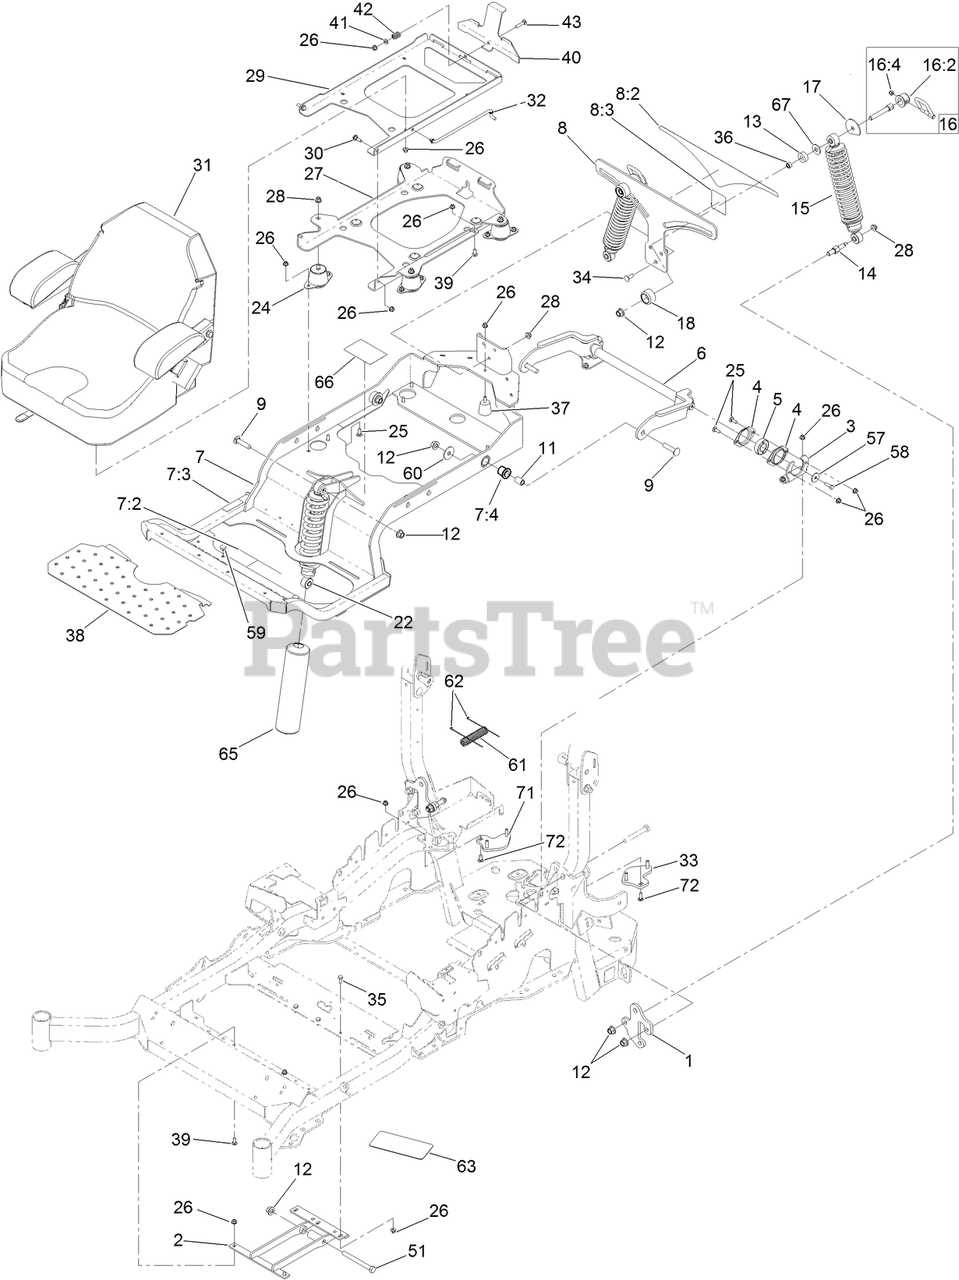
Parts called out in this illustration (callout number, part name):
1	PLATE-MOUNT, SHOCK
2	MOUNT-LOWER
3	BRACKET-BEARING
4	HOUSING-BEARING, FLANGE
5	BEARING
6	ARM-TRAILING
7	SUBFRAME ASM
7:2	DECAL-DANGER
7:3	DECAL-BRAKE, PARKING
7:4	BUSHING-FLANGE
8	BRACKET-MOUNTING
8:2	DECAL-ADJUSTMENT, RIDE
8:3	DECAL-LOCK, CAM
9	SCREW-CARR
11	SPACER-ALUMINUM
12	NUT-LOCK
13	SPACER
14	BOLT-SHOULDER
15	SHOCK-SPRING
16	CAM LOCK ASM
16:2	CAP-LOCK
16:4	NUT-HEX
17	PLATE-STOP
18	KNOB-FRONT
22	SHOCK-SPRING
24	ISOLATOR-SEAT
25	BOLT-CARR
26	NUT-HF, NI
27	PLATE-SUPPORT, ISO SEAT
28	NUT-HF, NI
29	PLATE-FRAME, SEAT
30	SCREW-SHOULDER
31	SEAT-STANDARD
32	ROD-PROP
33	LH PLATE ASM (W/STUDS)
34	SCREW-CARR
35	SCREW-HH
36	BEARING-NEEDLE
37	BUMPER-RUBBER
38	FLOORPAN
39	SCREW-CARR
40	PLATE-LATCH,SEAT
41	WASHER-PLAIN
42	SPRING-COMPRESSION
43	BOLT-CARR
51	SCREW-HH
57	Washer-Flat
58	SCREW-HH, THREAD LOCKING
59	BUMPER
60	WASHER-THRUST
61	COVER-HOSE
62	TIE-CABLE
63	TREAD-GRIP
65	COVER-SHOCK
66	DECAL-SERVICE AID
67	WASHER-FLAT
71	RH PLATE ASM (W/STUDS)
72	SCREW-CARR
